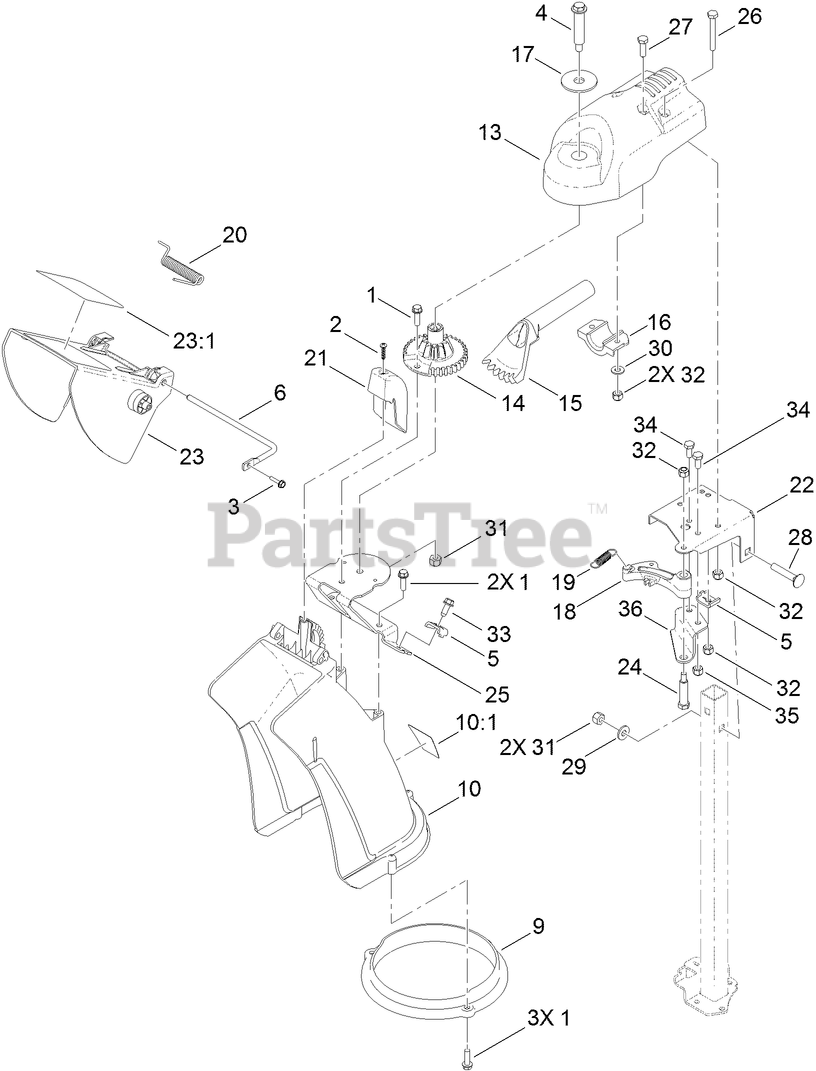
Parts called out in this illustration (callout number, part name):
1	SCREW-HWH
2	SCREW-PPH
3	SCREW-HWH
4	BOLT-SHOULDER
5	CLAMP-CABLE
6	ROD-DEFLECTOR
9	RING-CHUTE
10:1	DECAL-GUARANTEE
13	MOUNT-CHUTE, DISCHARGE
14	GEAR-CHUTE
15	GEAR-BEVEL
16	MOUNT-GEAR, BEVEL
17	WASHER-FLAT
18	LATCH-CHUTE
19	SPRING-LATCH, CHUTE
20	SPRING-TORSION
21	CHUTE-COVER
22	BRACKET-SUPPORT, CHUTE
23	DEFLECTOR-CHUTE
23:1	DECAL-DANGER
24	BOLT-SHOULDER
25	BRACKET-MOUNT, CHUTE
26	SCREW-HH
27	SCREW-HH
28	BOLT-CAR
29	WASHER-FLAT
30	WASHER-FLAT
31	NUT-LOCK, NI
32	NUT-LOCK, NI
33	SCREW-HWH
34	SCREW-HH
35	NUT-LOCK, NI
36	BRACKET-SUPPORT, LATCH
